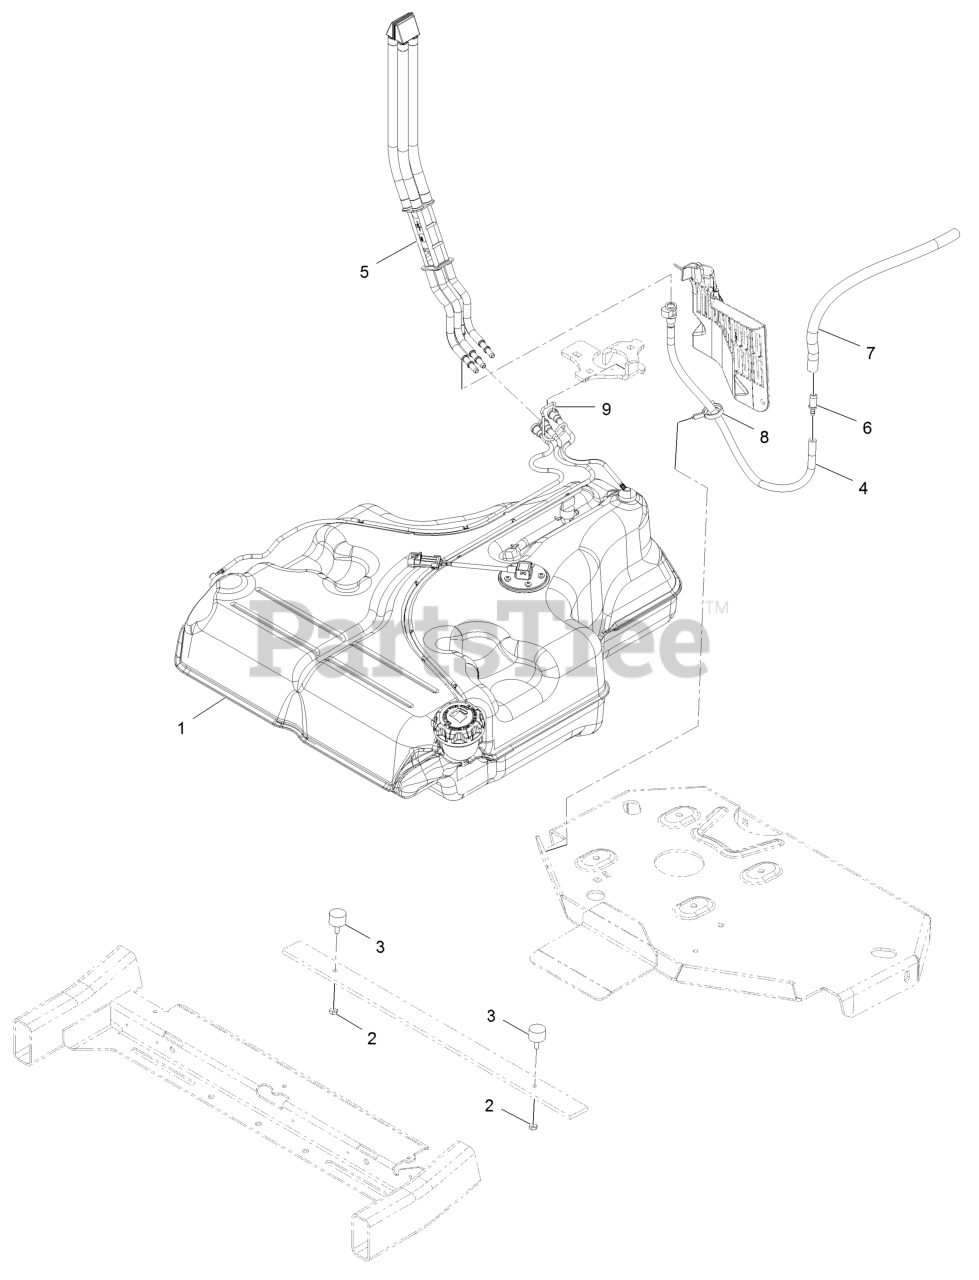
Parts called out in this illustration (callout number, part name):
2	NUT-JAM
4	HOSE ASM
5	FUEL MANIFOLD VENT ASM
6	FITTING-STRAIGHT
7	HOSE-FUEL
8	CLAMP-HOSE
9	RETAINER-LINE, VAPOR
